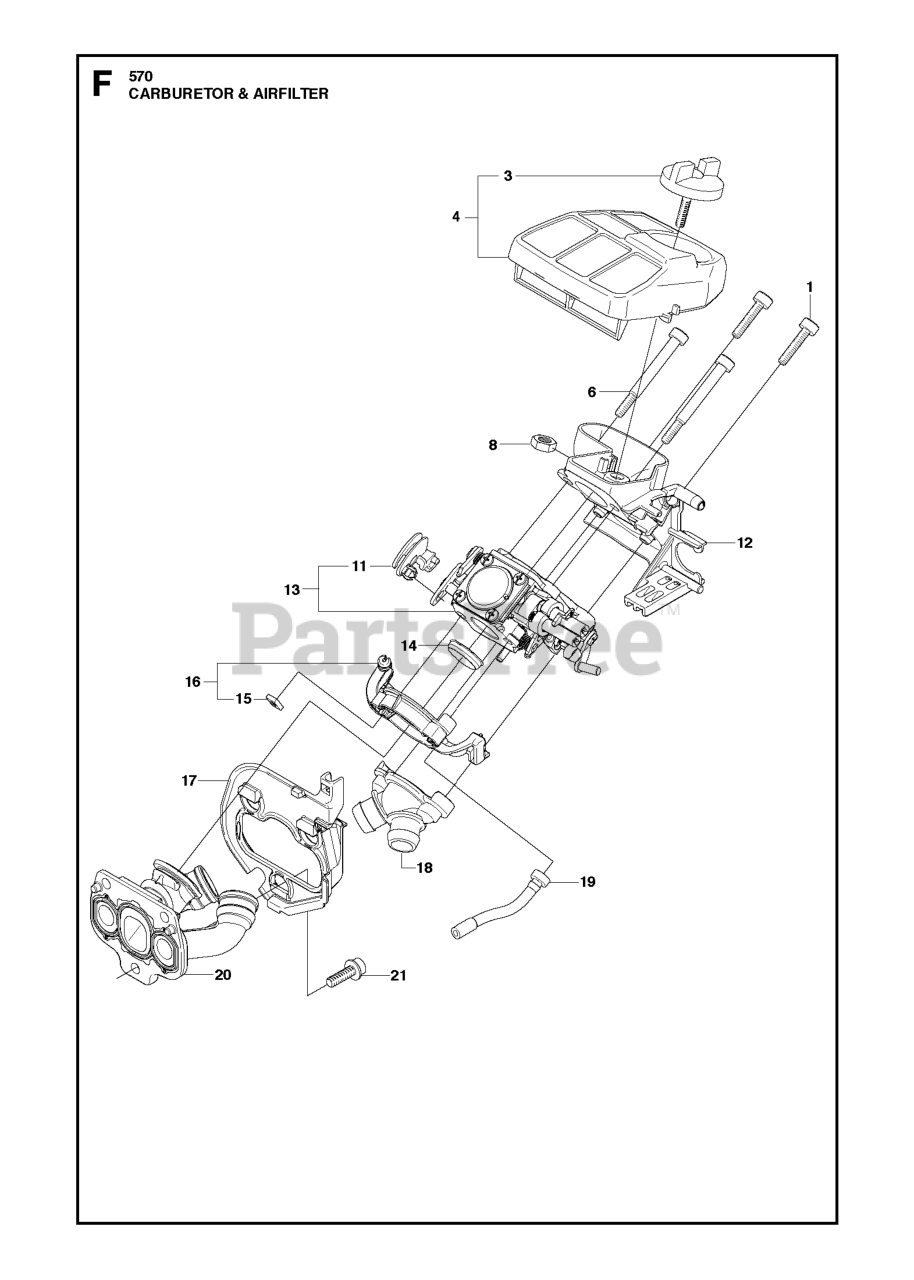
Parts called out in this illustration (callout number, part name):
4	RP AIR FILTER
4	AIR FILTER
6	SCREW 4X46
12	FILTER HOLDER
13	RP CARBURETOR
20	PIPE
